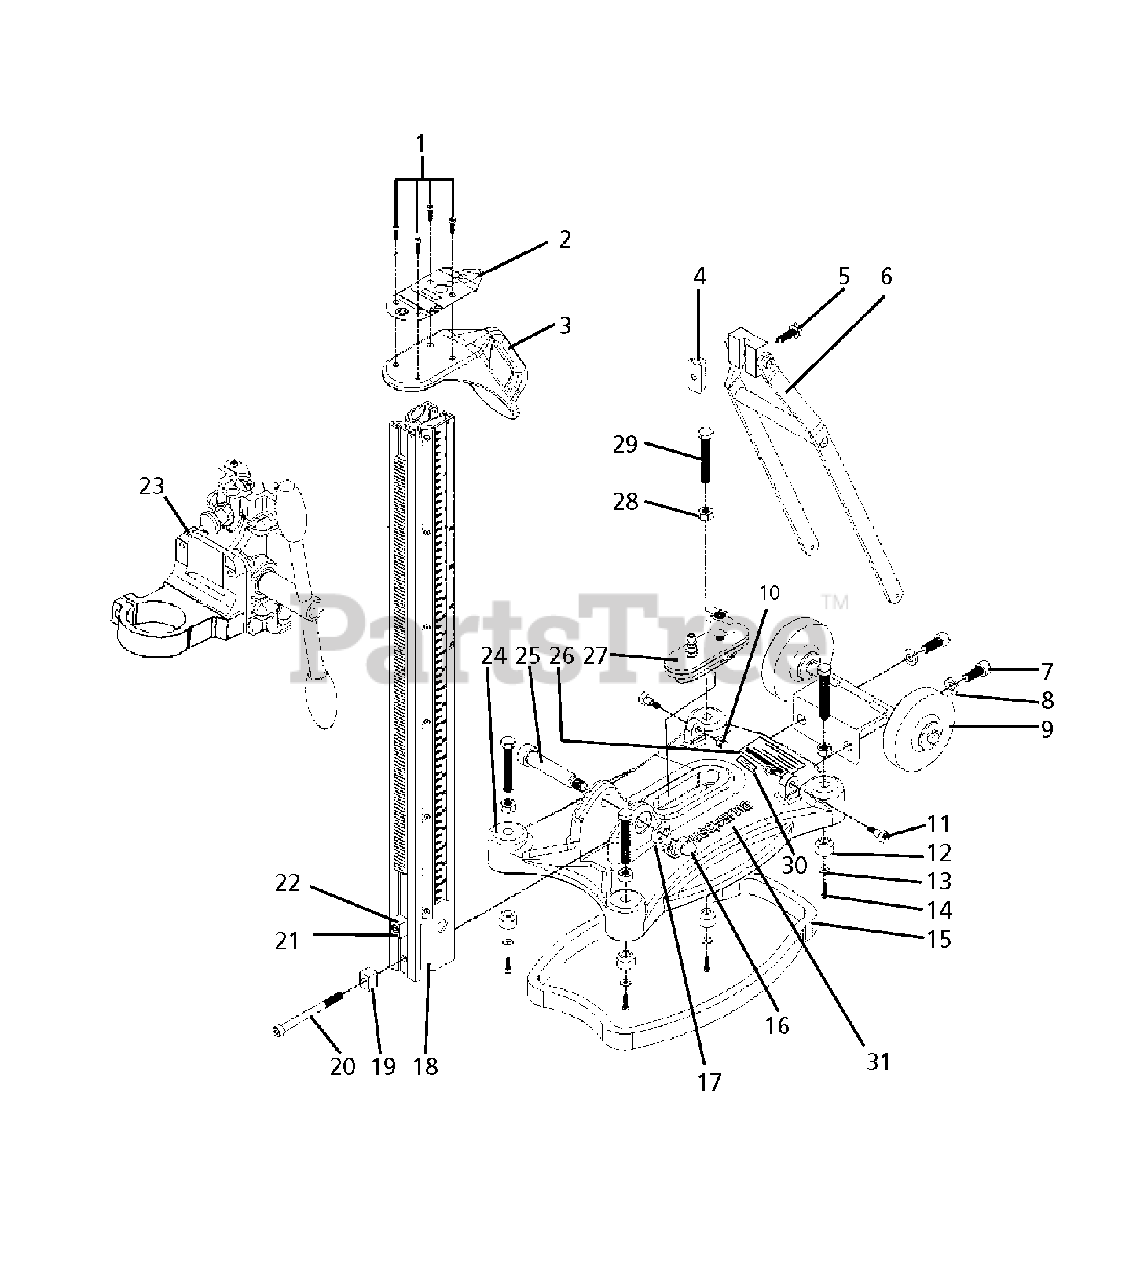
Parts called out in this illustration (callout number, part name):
1	M4X16 SOCKET HEAD CAP/SCREW
14	M4X16 SOCKET HEAD CAP/SCREW
23	DSC CARRIAGE ASSEMB HUSQVARNA
